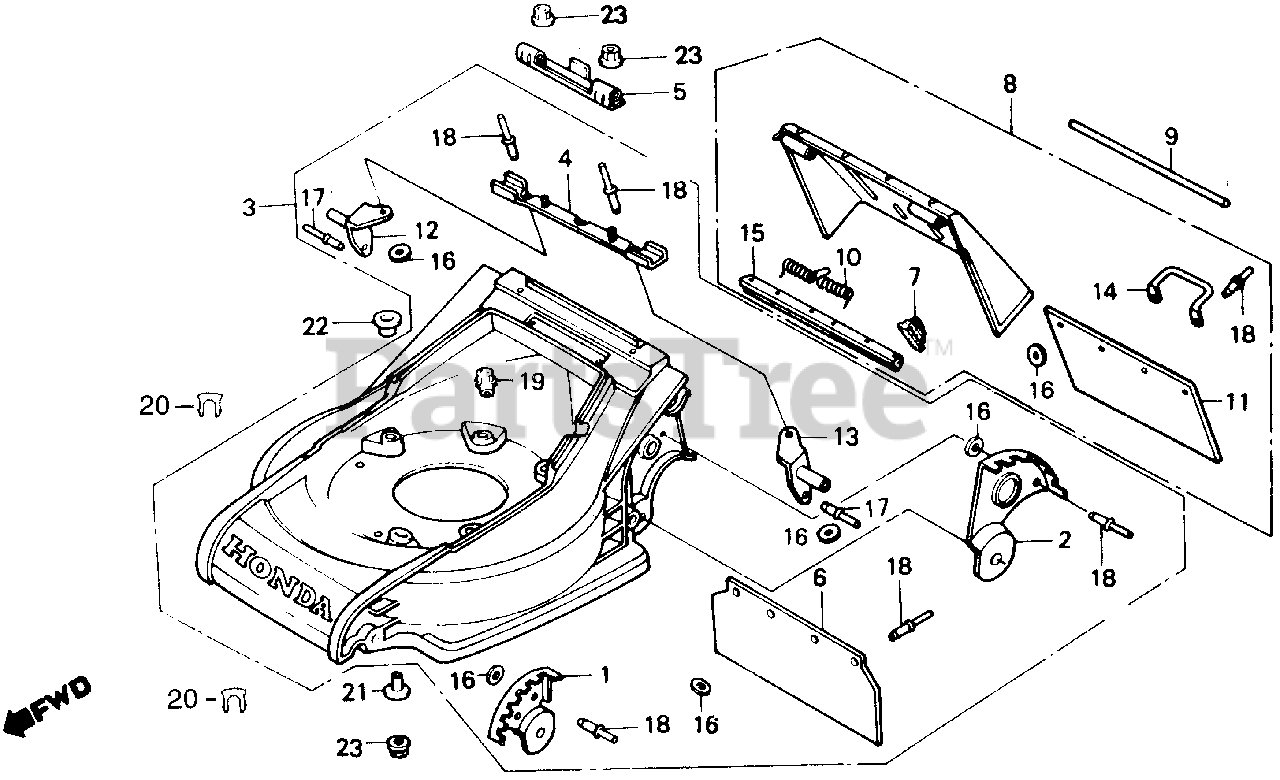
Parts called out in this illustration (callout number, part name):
1	PANEL, FR. ADJUSTING
2	PANEL, RR. ADJUSTING
3	HOUSING, CUTTER *NH246* (LOOSY GRAY)
4	HINGE, DISCHARGE GUARD (NOT AVAILABLE)
5	HINGE, DISCHARGE GUARD (NOT AVAILABLE)
6	SHIELD, SAFETY
7	STOPPER, DISCHARGE GUARD
8	GUARD, DISCHARGE (NOT AVAILABLE)
9	SHAFT, DISCHARGE GUARD
10	SPRING, GUARD RETURN
11	SHIELD, DISCHARGE GUARD (NOT AVAILABLE)
12	STAY, R. HANDLE
13	STAY, L. HANDLE
14	GRIP, DISCHARGE GUARD (NOT AVAILABLE)
15	SEAL, DISCHARGE GUARD (NOT AVAILABLE)
16	WASHER, STOPPER (14MM)
16	WASHER, STOPPER
17	RIVET, BLIND (4.8MM)
18	RIVET, BLIND (4.8X18.2) (NOT AVAILABLE)
19	CAP, HOUSING
20	CAP, DRAIN
21	COLLAR, ENGINE BED
23	NUT, FLANGE (6MM)
